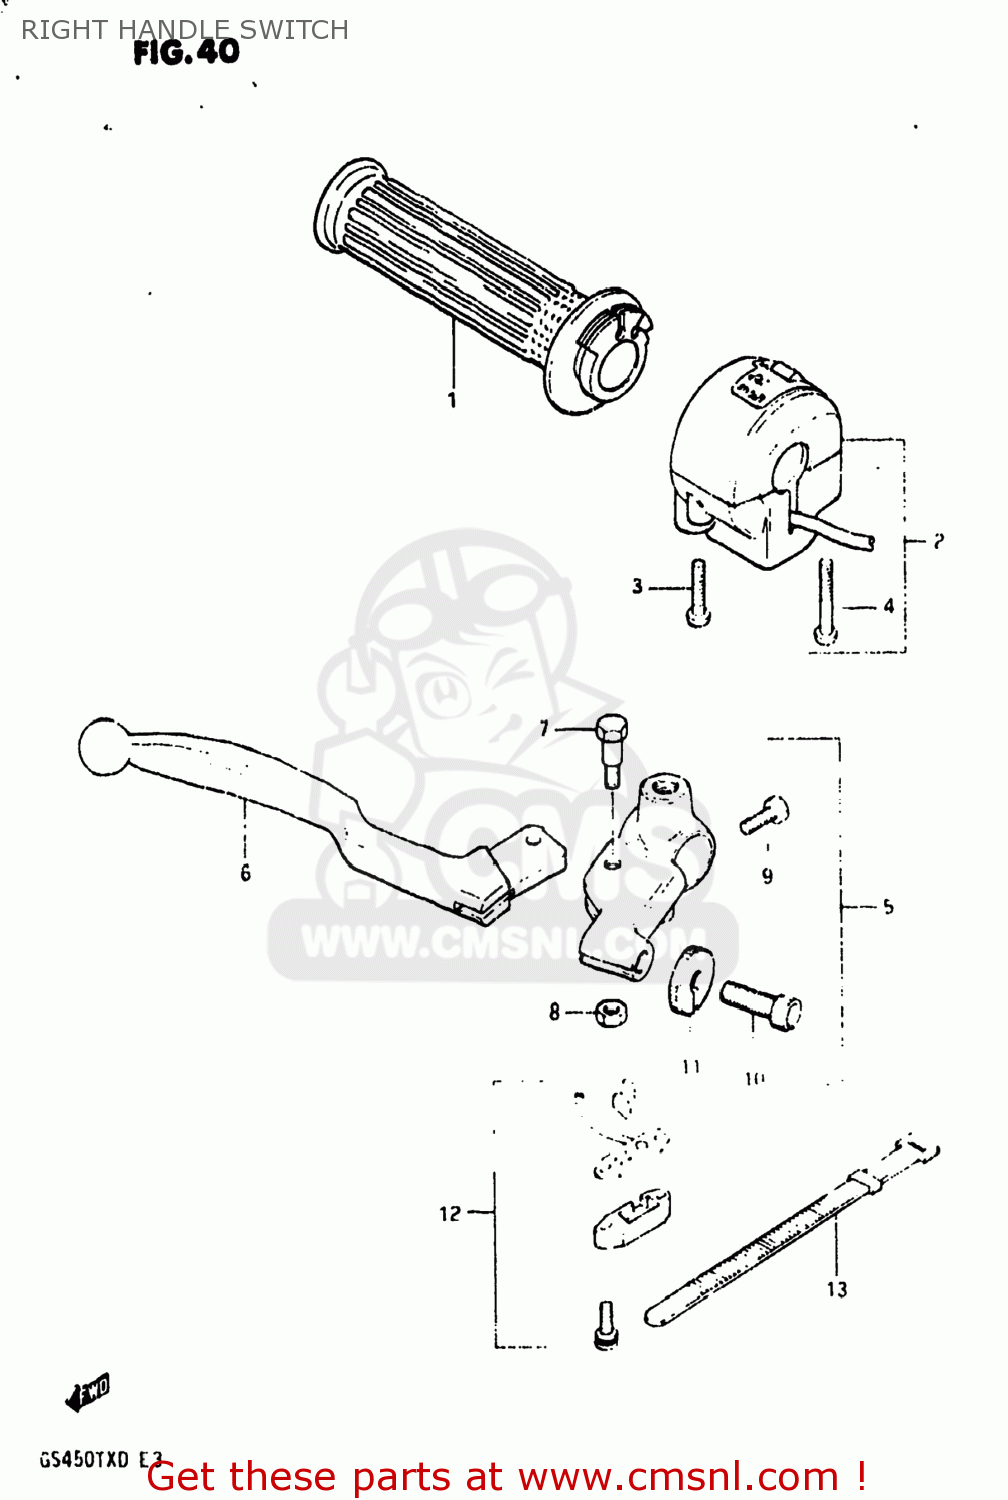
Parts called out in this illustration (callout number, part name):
1	GRIP,THROTTLE
2	SWITCH ASSEMBLY,HANDLE,RIGHT
3	SCREW
4	SCREW
5	LEVER ASSEMBLY,BRAKE
6	LEVER,BRAKE
7	BOLT,LEVER
8	NUT 6MM
9	BOLT,CLUTCH LEVER HOLDER
10	ADJUSTER,CABLE
11	NUT,CABLE ADJUSTER LOCK
12	SWITCH ASSEMBLY
13	CLAMP(L:120)
